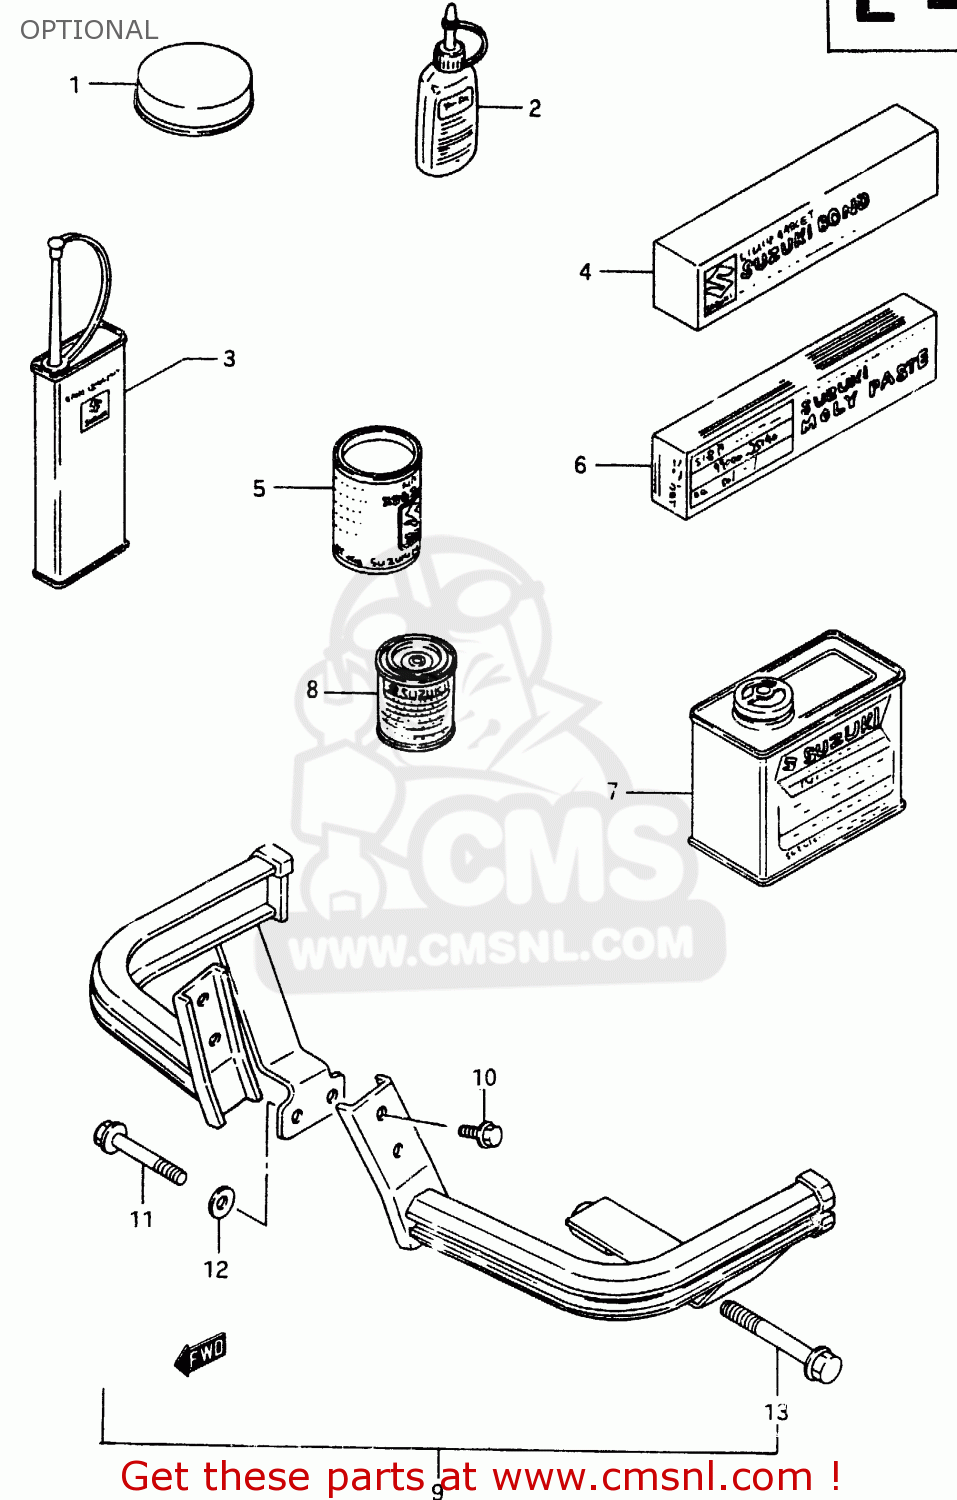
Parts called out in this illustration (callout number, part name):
1	GREASE,PBC FOR BRK PAD 20G
2	THREAD LOCK NO.1342
3	THREAD LOCK NO.1401 CLEAR 200G
4	LIQUID GSKT NO.1207B 100G BLK
5	GREASE(C)EP2 LITHIUM 150G
6	SUZUKI MOLY PASTE
7	PAINT (MEDIUM GOLD)
8	PAINT,BLACK
9	BAR SET, ACCESSORY
10	BOLT
11	BOLT
12	WASHER (8.5X24X2.3)
13	BOLT(10X125)
